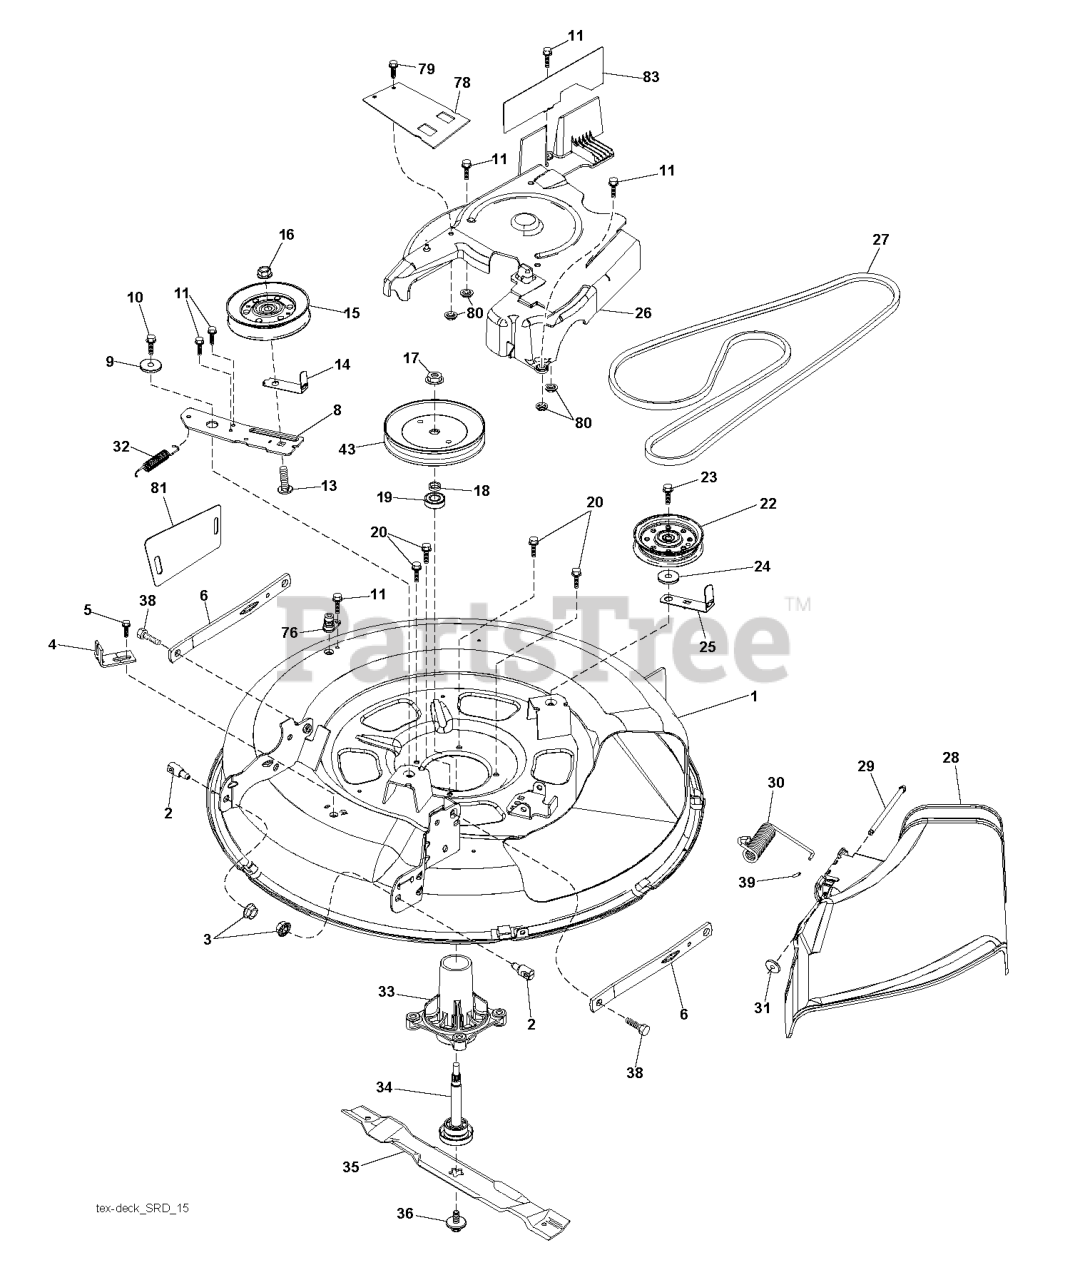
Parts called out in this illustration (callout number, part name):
1	DECK.WELDMENT.30"SRD.BLACK
2	STUD.FASTNER.W/ANTI-ROTATE
3	NUT LOCK HEX FLANGE 5/16-18
4	BRACKET.CLUTCH.CABLE
5	BOLT.5/16HEX.WHS.HD
6	ARMS.SUSP.MOWER.REAR.SRD
8	ARM.IDLER.30"SRD
9	SPACER.RETAINER
10	SCREW 3/8-16X1
11	SCREW.1/4-20X5/8
13	BOLT.3/8-16X1.50
14	KEEPER, BELT IDLER
15	PULLEY.IDLER.4.25
16	NUT LOCK FLG 3/8-16 UNC
17	NUT.FLANGE.LOCK.TOP
18	WASHER.SPACER.MANDREL
20	SCREW, WASHER HEAD
22	PULLEY.IDLER.FLAT.UNPLATED
23	SCREW LT
24	WASHER
25	KEEPER.BELT.30"SRD
26	COVER.ASM.MANDREL.30"
27	V-BELT.DRIVE.MOWER.30"
28	SHIELD.DEFLECT.MWR.30S.BLACK
29	PIN.HINGE.30".SRD
30	SPRING.TORSION.DEFLECT
31	NUT PUSH M
32	SPRING.MOWER.DRIVE.ELECTRIC
33	RP.HOUSING.MANDREL.4PT.
34	SHAFT.ASM.MDRL.N/GREASE.38
35	BLADE, MULCH.LRV30
36	BOLT.WASHER.ASM.7/16-2
38	BOLT.SHOULDER
39	CAP-SLEEVE LT
43	PULLEY, MANDREL 6.5 PD
76	PORT.WASHOUT
78	GUARD ARM CLUTCH
79	SCREW.HI-LO.CONSOLE
80	PALNUT 1/4
81	SHIELD SUSPENSION
83	GUARD LEFT
